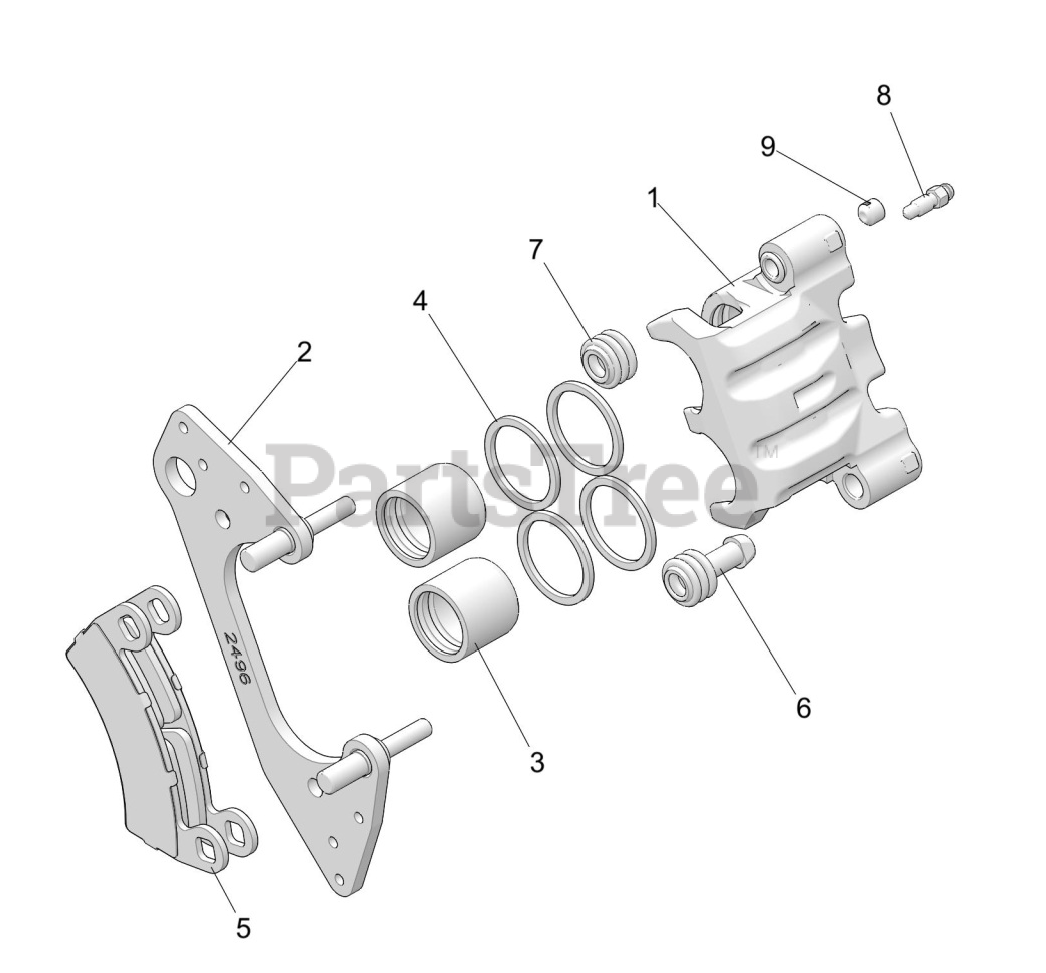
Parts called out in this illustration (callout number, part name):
1	ASM-BRK-CAL-L-DB1-3/8-GROOVED
1	ASM-BRK-CAL-R-DB1-3/8-GROOVED
2	ASM-CAL/MNT,DB,1-3/8,METRIC
3	PISTON-BRAKE,1.375,AL,GROOVED
4	SEAL-CALIPER,INNER,1.375"
5	KIT-ASM,PAD,BRAKE,DB,1.375
6	BOOT-PIN BUSHING
7	BOOT-PIN SEAL
8	SCR-M7X1.0,BLEEDER,OLIVE D
9	SCR-M10X1.0X8,SOC SET-OD
